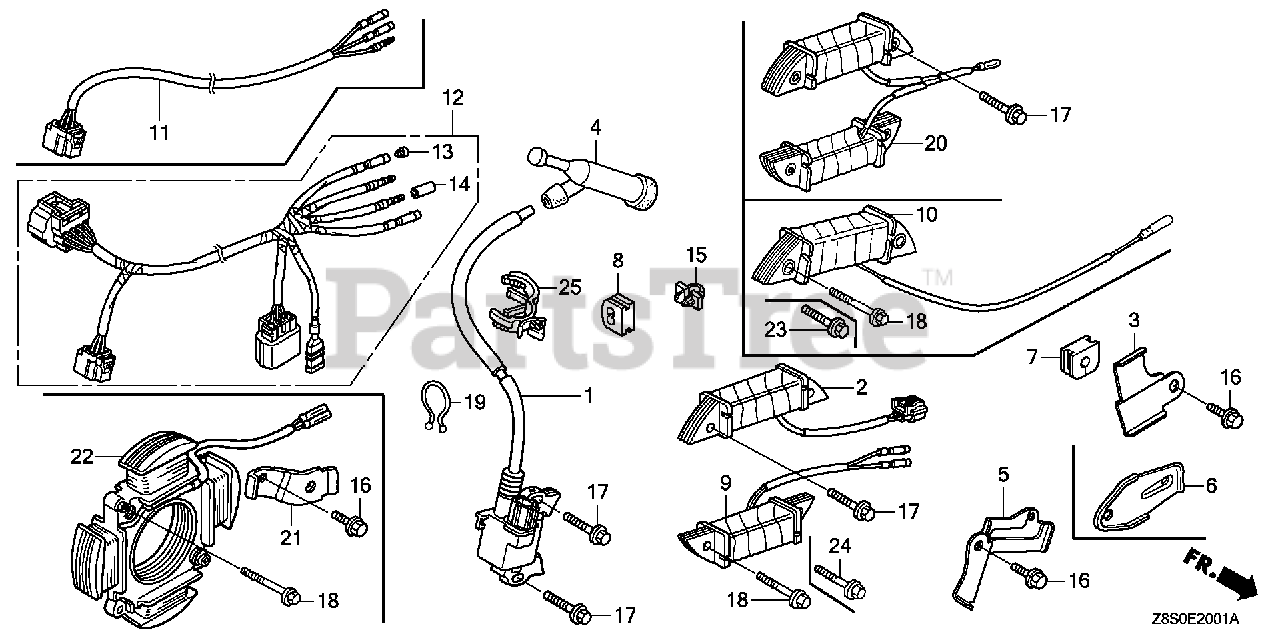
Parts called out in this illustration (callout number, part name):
1	COIL ASSY., IGNITION
2	COIL ASSY., POWER
3	BRACKET B, HARNESS
4	CAP ASSY., NOISE SUPPRESSOR (NGK Y-EZD)
5	CLAMP, WIRE
7	GROMMET, WIRE
8	GROMMET, WIRE
9	COIL ASSY., CHARGE (2.9A)
12	WIRE HARNESS ASSY., ENGINE
13	PLUG, CONNECTOR (INNER)
14	PLUG, CONNECTOR (OUTER)
16	BOLT, FLANGE (6X12) (CT200)
17	BOLT, FLANGE (6X28) (CT200)
18	BOLT, FLANGE (6X32) (CT200)
